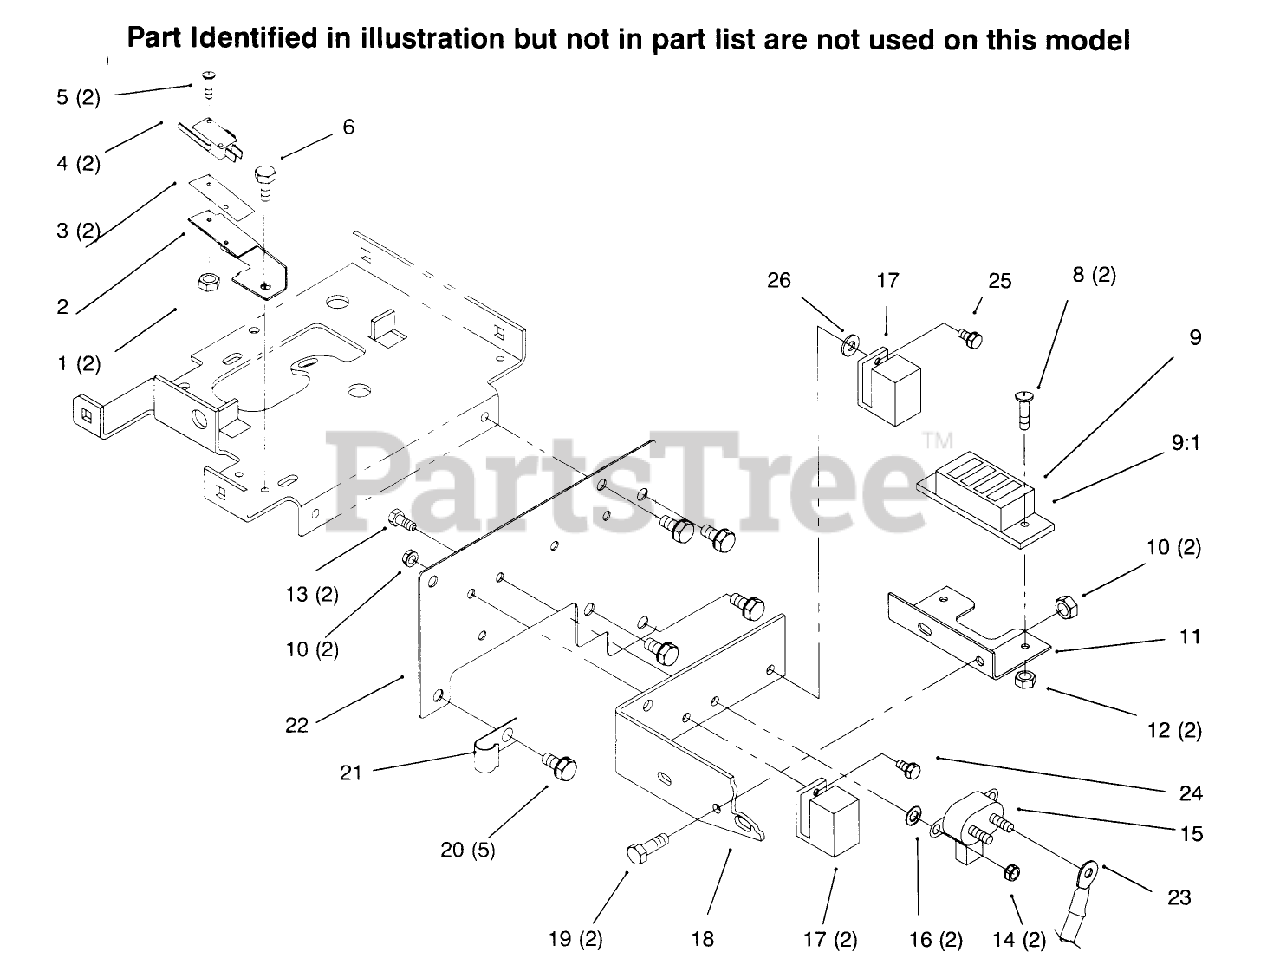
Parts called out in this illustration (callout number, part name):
1	NUT-HEX, NYL INS
3	BARRIER - SWITCH
4	SWITCH
5	SCREW-PHL 4-40X1 1/4
6	SCREW-HWH
8	SCREW-PAN
10	NUT-LOCK, NI
14	NUT-HEX
16	WASHER-LOCK/EXT
17	RELAY
18	BRACKET-BELT*B
19	SCREW-HH
21	CLIP
